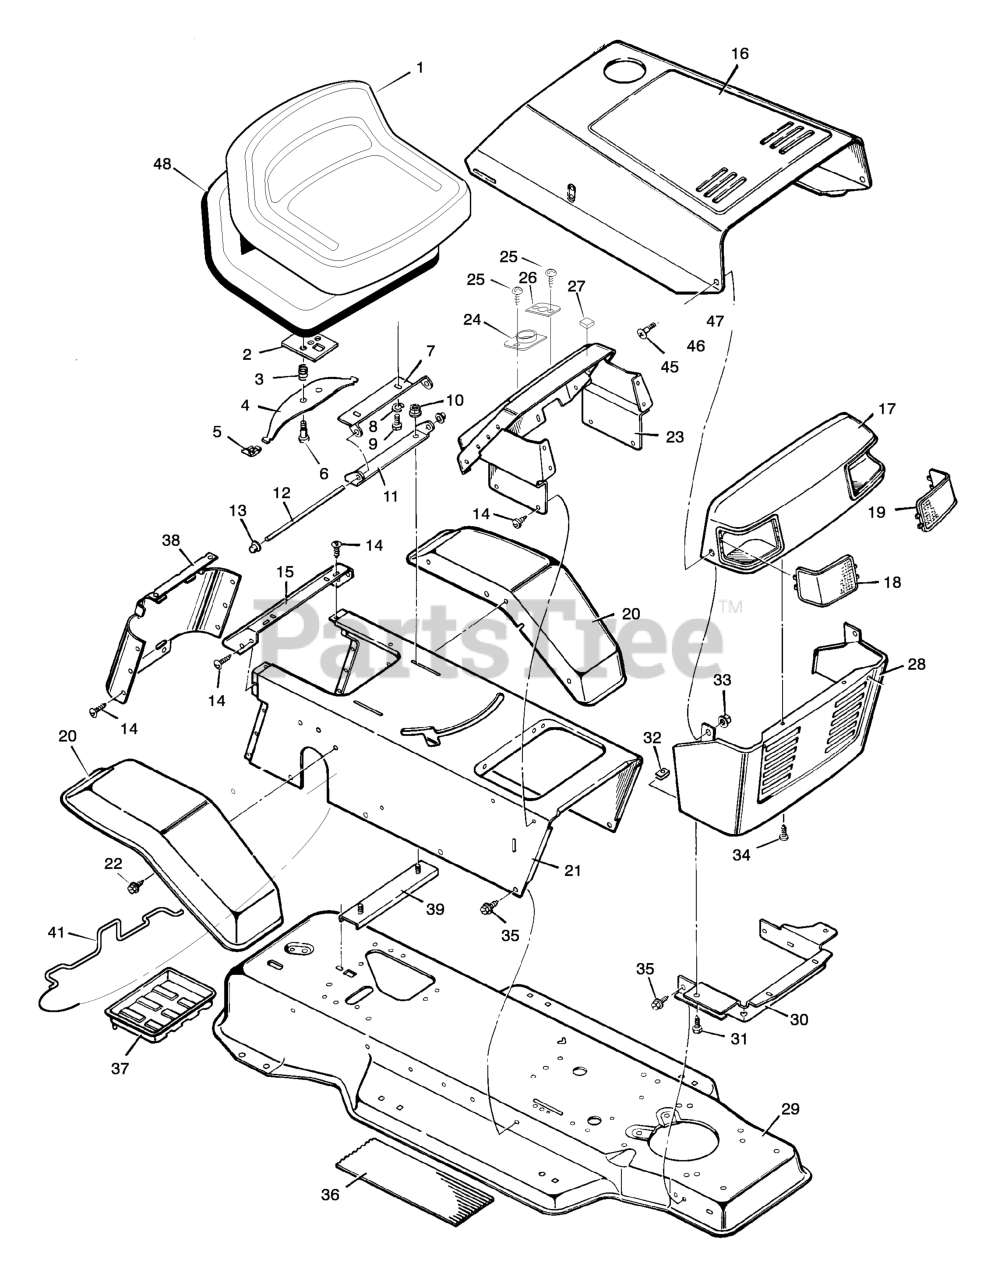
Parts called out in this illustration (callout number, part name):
2	Plate Assembly, Switch
3	Spring, Compression
4	Spring, Seat
5	Glide, Spring
6	Bolt, Shoulder
7	Support, Seat
8	Lockwasher
9	Bolt, Hex
10	Locknut, Flange
11	Bracket, Pivot
12	Rod, Pivot
13	Cap, Push On
14	Screw, Tap
15	Fender, Apron
17	Grille, Upper
18	Lens, Right
19	Lens, Left
21	Console Assembly
23	Dash Panel
24	Bearing, Steering
26	Bearing
27	Bumper
28	Grill, Lower
29	Frame Assembly
30	Support, Grill
33	Locknut, Flange
34	Fastener, Plastic
37	Tray, Battery
38	Cap, Console
39	Channel Assembly
41	Clamp, Battery
45	Bolt, Shoulder
48	Pan, Seat (with foam)
